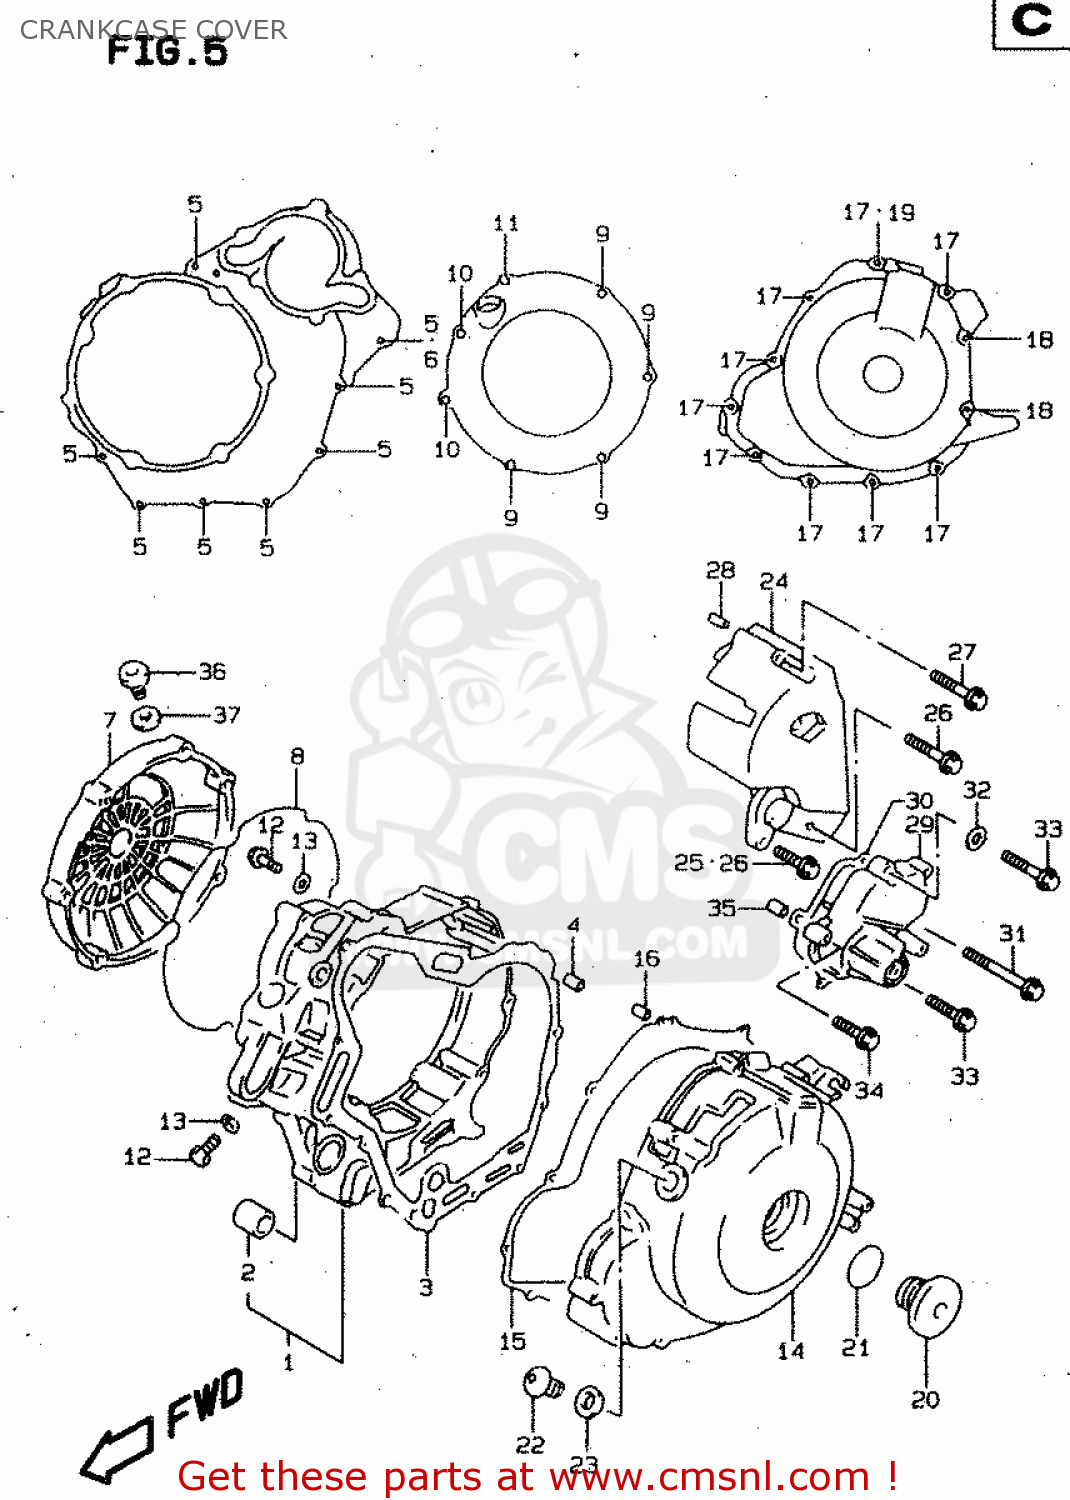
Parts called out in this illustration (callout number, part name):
1	COVER,CLUTCH
2	LENS,OIL LEVEL CHECK
3	GASKET,CLUTCH COVER (NAS)
4	PIN
5	BOLT
6	GASKET(5.8X11X1.2) (NAS)
7	COVER,CLUTCH OUTER
8	O RING,CLUTCH COVER OUTER
9	BOLT
10	BOLT
11	BOLT
12	BOLT
13	GASKET(6.2X11X1).2 (NAS)
14	COVER,MAGNETO
15	GASKET,MAGNETO COVER (NAS)
16	PIN
17	BOLT
18	BOLT
19	GASKET(5.8X11X1.2) (NAS)
20	PLUG
21	O RING(D:3.1,ID:32.7)
22	PLUG,14X12
23	GASKET(13.8X18.8X4.8) (NAS)
24	COVER,ENGINE SPROCKET
25	BOLT
26	BOLT
27	BOLT
28	PIN
29	COVER,GEAR SHIFT
30	GASKET,GEAR SHIFT COVER (NAS)
31	BOLT(6X105)
32	GASKET(5.8X11X1.2) (NAS)
33	BOLT
34	BOLT
35	PIN
36	PLUG
37	O RING(D:3.1,ID:16.8)
